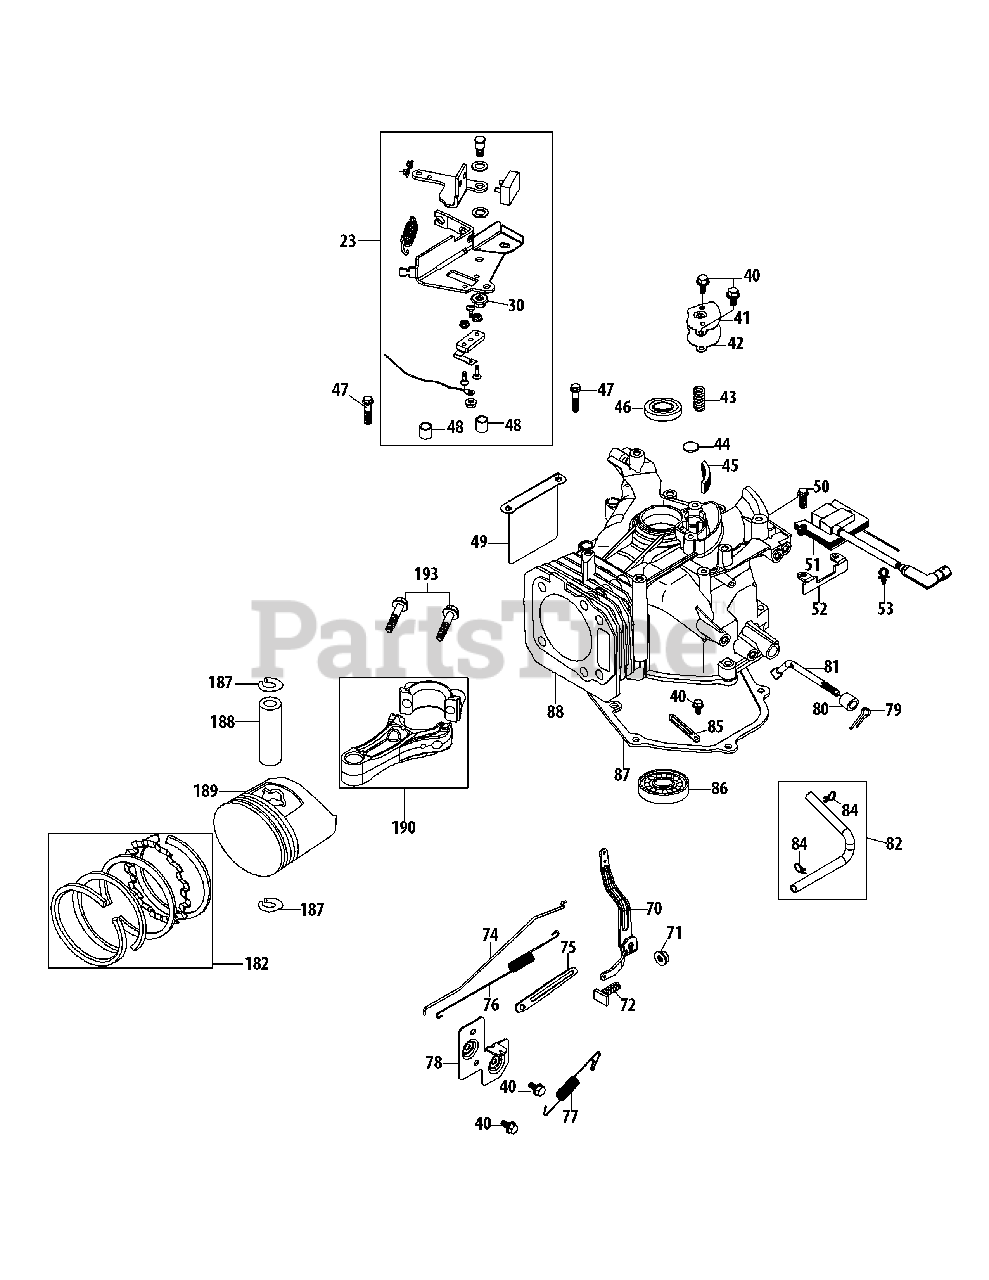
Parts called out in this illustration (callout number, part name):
23	Stop Switch And Brake Assembly
30	Nut M 8 - 1.25
40	Bolt M6×14
41	Breather Cover Plate
42	Breather Gasket
43	Breather Valve Spring
44	Breather Valve
45	Mesh Screen
46	Upper Crankshaft Seal
47	Bolt M6×35
48	Engine Brake Spacer
49	Label Bracket
50	Bolt M6×18
51	Ignition Coil Assembly
52	Ignition Coil Bracket
53	Plastic Clamp 6.3×8
70	Governor Arm
71	Nut M6
72	Governor Arm Bolt
74	Throttle Linkage
75	Flexible Clamp
76	Throttle Linkage Spring
77	Governor Return Spring
78	Component Bracket
79	Clip - Governor Shaft
80	Governor Seal
81	Governor Arm Shaft
82	Breather Hose Asm - Includes Hose & Clamps
84	Breather Hose Clamp
85	Flexible Clamp
86	Main Bearing
87	Crankcase Cover Gasket
88	Short Block Assembly
182	Piston Ring Set
187	Piston Pin Snap Ring
188	Piston Pin
189	Piston
190	Connecting Rod Assembly
193	Connecting Rod Bolt
